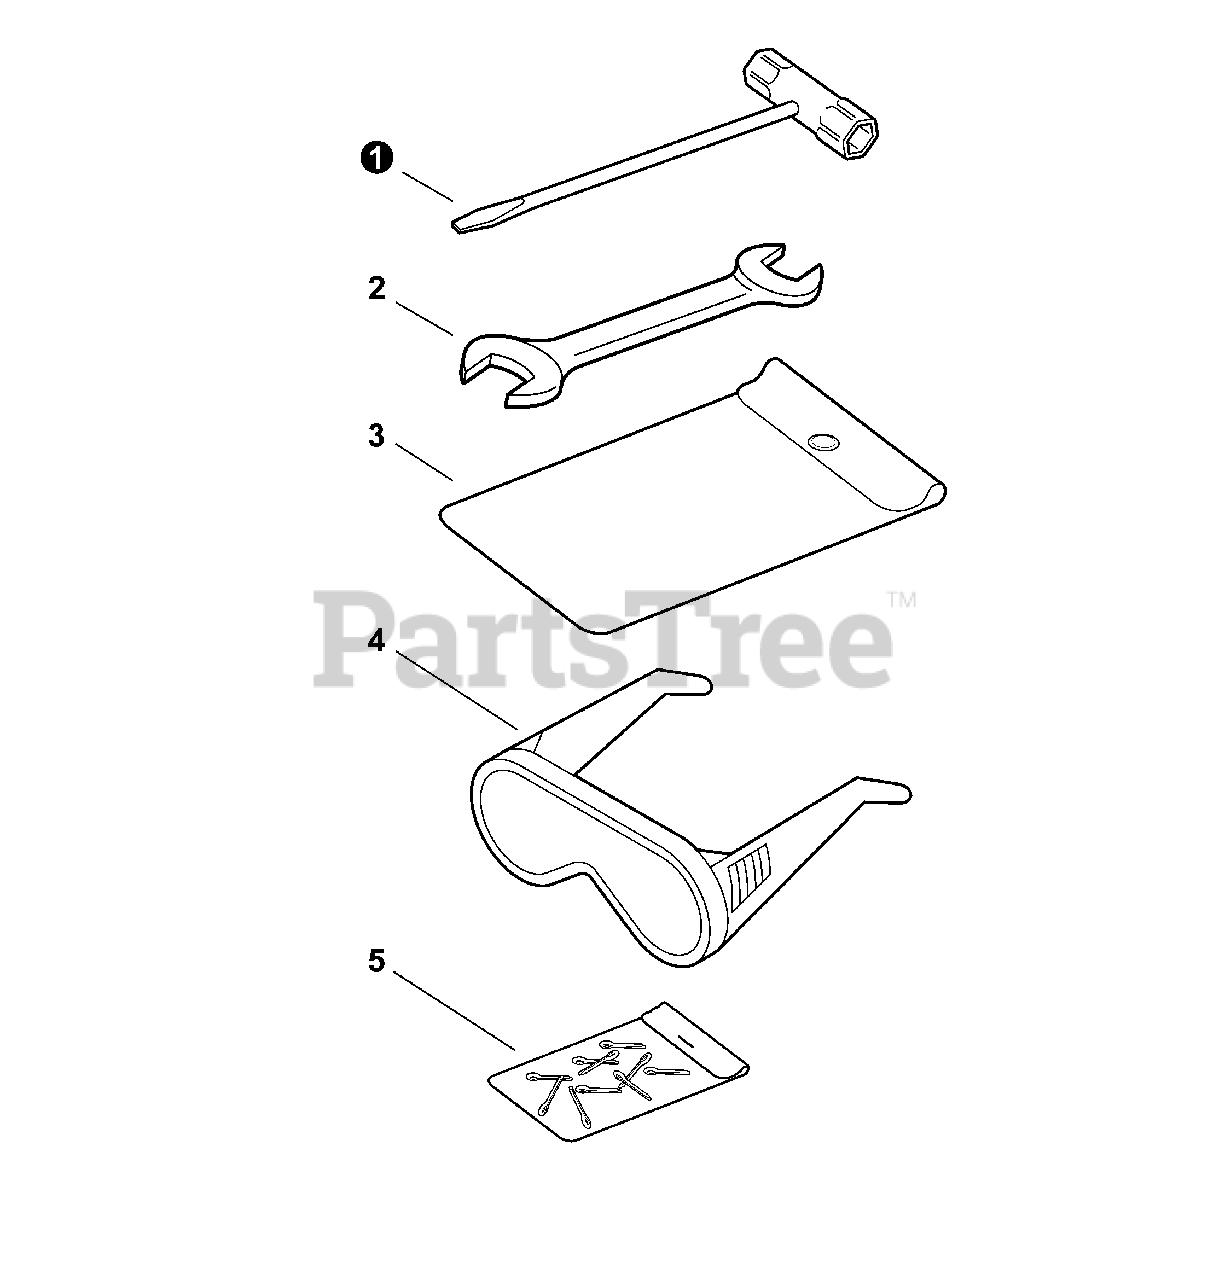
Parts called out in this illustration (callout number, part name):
1	T-WRENCH - 10×19mm
2	SPANNER - 8×10mm
3	BAG,TOOL
4	GOGGLES
5	PIN, SPLIT - 2×22
